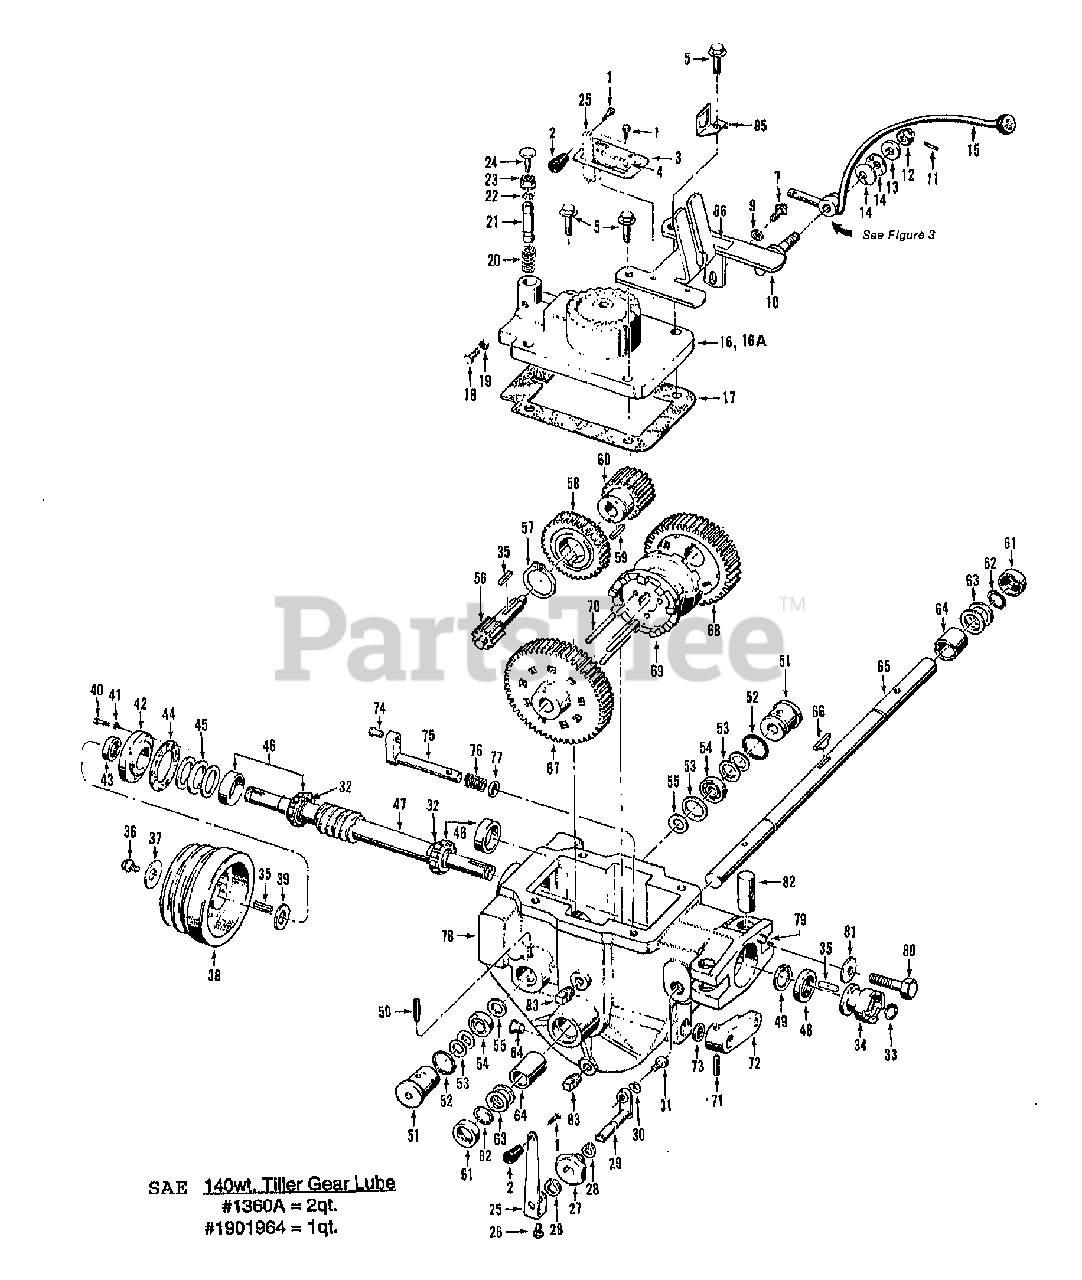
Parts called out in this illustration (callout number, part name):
1	SCR 10-32
2	KNOB-TAPERED
3	PLATE-TINE ENGAGE W/DECAL
4	DECAL-TINE ENGAGE
5	SCR-HFLK 3/8-16X1.50
7	SCR-HFLK 5/16-18X.75 ZP
9	WASHER-FLAT 5/16 SAE
10	BRKT-H HOOD 2149
11	PIN-SPRING .125 X 1
12	NUT
12	NUT-HEX 1/2-20 CALL TECH. SERVICE DEPT. FOR TIGHTENING INSTRUCTIONS.
13	WASHER-# SHOULDER ZP (SHOULDER FACES DISC WASHERS)
14	WASHER-# 1.97X1X.118 (CONCAVE SURFACES FACE EACH OTHER)
15	LEVER
16	COVER-TRANS RED 2523
16A	ASSM-TRANS COVER OPC
17	GASKET-TRANS COVER
18	SCR-HH 5/16-18X1.0 G5 ZP (REMOVE WITH CARE) SEE REF.#'S 20 & 21
19	NUT-HEX 5/16-18 ZP
20	SPRING-REV PLUNGER ZP (REMOVE WITH CARE)
21	ASSM-NEUTRAL PLUNGER (REMOVE WITH CARE) INCLUDES #9504 CLIP RING(REF.#22)
22	RING-KLIP EXT .594 ID ZP
23	NUT-HFLK 3/8-16 ZP
24	SCR 3/8-16X1.5 UNC-2AG
25	LEVER-ECCENTRIC RED (ALSO SEE REF.#'S 1,2 3 AND 4 LISTED ABOVE)
26	SCR-HH 1/4-20X.5 GR5 YEL
27	BUSHING-.87X.5X.62 ECC
28	RING-RETAINING 5100-50
29	SHAFT-WELD ECCENTRIC
30	WASHER-LK .25 HI-COLLAR
31	SCR-HXSKT 1/4-20X.38 G8
32	SHIM-1.0X.7656X.062 SHOULDER(DRIVE SHAFT)
33	RING-RETAIN EXT .707 ID
34	KIT-CLUTCH DOGS TILLER
35	KEY-.188 SQX1.0 (USED ON DRIVE SHAFT AND PINION SHAFT)
36	SCR-HH 5/16-24X.75 G5 ZP
37	WASHER-.827X.331X.098
38	PULLEY-TRANS MACH
39	WASHER-SHLDR HARDENED
40	SCR-HH 1/4-20X.75 G5 ZP
41	WASHER-LK .25 ZP
42	COVER-FRONT
43	SEAL-PINION SHAFT PT/85030/00
44	GASKET-BRG COVER
45	SHIM-1.75X1.5X.01
45	SHIM-1.75X1.5X.03
45	SHIM-1.75X1.5X.005
45	SHIM-1.75X1.5X.062
46	KIT-BRG CONE&RACE-DRIVESHAFT
47	KIT-WHEELDRIVE ROLL/WORM
48	SEAL-OIL DRIVESHAFT
49	RING-RETAINING 5000-181
50	PIN-SPIROL .25 X 2.0 (REF.#51)
51	PLUG-PINION BRG W/RING (REF.#52)
52	RING-O 1 ID
53	SHIM-1.234X1.015X.033
53	SHIM-1.234X1.015X.062
53	SHIM-1.234X1.015X.01
54	BRG-BALL (7 BALLS)
55	WASHER-# 1X.484X.06
56	GEAR-SPLINE 10 TEETH MACH (DRIVES SLOW SPEED WHEEL GEAR)
57	RING-RETAINING 5100-150
58	GEAR-WORM MACH
59	KEY
60	GEAR-SPUR 20 TEETH MACH (DRIVES FAST SPEED WHEEL GEAR)
61	SEAL-OIL WHEELSHAFT
62	RING-HEAVY EXT .906 ID
63	SHIM-1.375X1.015X.062
63	SHIM-1.375X1.015X.03
63	SHIM-1.375X1.015X.015
63	SHIM-1.375X1.015X.01
63	SHIM-1.375X1.015X.005
64	BUSHING-1.25X1.005X1.5
65	KIT-WHEELSHAFT
66	KEY-HI PRO .25X1.812
67	GEAR-SPUR 56 TEETH MACH
68	GEAR-SPUR 46 TEETH MACH
69	CLUTCH-MACH
70	PIN-CLUTCH .25 2.65
71	PIN-SPIROL .188 X 1.25
72	LEVER-ECC. #1029
73	SEAL-OIL ECCENTRIC
74	PIN-.375 X .72
75	SHAFT-ECCENTRIC HORSE TLR
76	SPRING .845 X 1.25
77	WASHER # .875 X .65 X .06
78	CASE-TRANS W/PIN
79	PIN-DRIVE .375X.75 ZP
80	SCR-HH 1/2-13X2.0 G5 ZP
81	WASHER-DISC SPRING
82	POST (TC) WITH THREADED HOLE FOR #9560 BOLT( REF.#80)
83	PLUG-PIPE 1/4 NPT
84	PLUG-CAP (RED)
85	CLIP-CONNECTOR (ALSO SEE PAGE 16)
86	DECAL-FWD INTERLOCK WIRE
